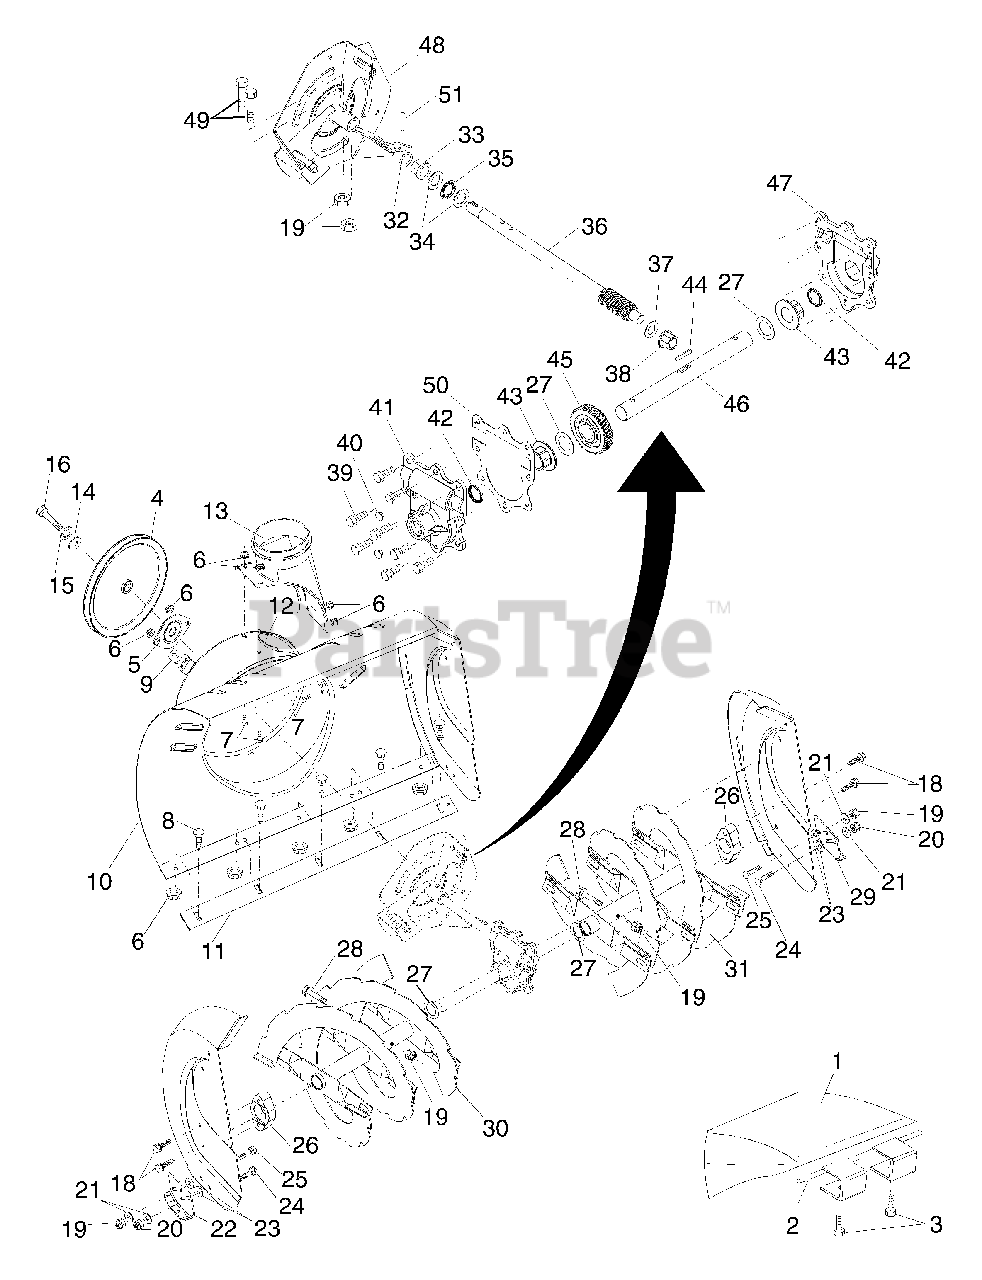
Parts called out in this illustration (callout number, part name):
1	Bag, Weight
2	Bracket, Weight Bag
3	Screw, Hex Head 5/16-18 x 1-1/2
4	Pulley, Impeller
5	Bearing Assembly, Flange
6	Nut, Hex Flange 5/16-18
7	Bolt, Flat Head, Carriage 5/16-18 x 5/8
8	Bolt, Carriage 5/16-1 8 x 5/8
9	Nut, Cage 3/8-16
10	Housing, Auger
11	Bar, Scraper
12	Bracket, Corner Discharge
13	Base, Discharge Chute
14	Washer, Flat
15	Washer, Lock 5/16
16	Screw, Hex Head 5/16-18 x 3/4
18	Screw, Hex Head 5/16 x 1
19	Nut, Hex Lock 1/4-20
20	Nut, Hex Lock 5/16-18
21	Washer, Flat
22	Skid Plate, RH
23	Washer, Nylon, Friction
24	Bolt, Carriage 5/16-18 x 3/4
25	Bolt, Shoulder
26	Bearing, Auger
27	Washer, Thrust, 1"
28	Bolt, Shoulder 1/4-20 x 2
29	Skid Plate, LH
30	Auger Assembly, RH
31	Auger Assembly, LH
32	O-Ring
33	Bushing, Flange 3/4
34	Washer, Thrust 3/4
35	Bearing, Thrust 3/4
36	Shaft, Impeller
37	Washer, Thrust 5/8
38	Bushing, Flange 5/8
39	Screw, Hex Head 5/16-18 x 3/4
40	Plug, Case
41	Housing, Gearbox, RH
43	Bushing, Flange, 1"
44	Key, Square 1/4 x 1/4 x 7/8
45	Gear, Worm
46	Shaft, Auger
47	Housing, Gearbox, LH
48	Impeller Assembly
49	Screw, Hex Head 1/4-20 x 1-5/8
50	Gasket, Gearbox
51	Pin, Roll 3/16 x 1-1/8
